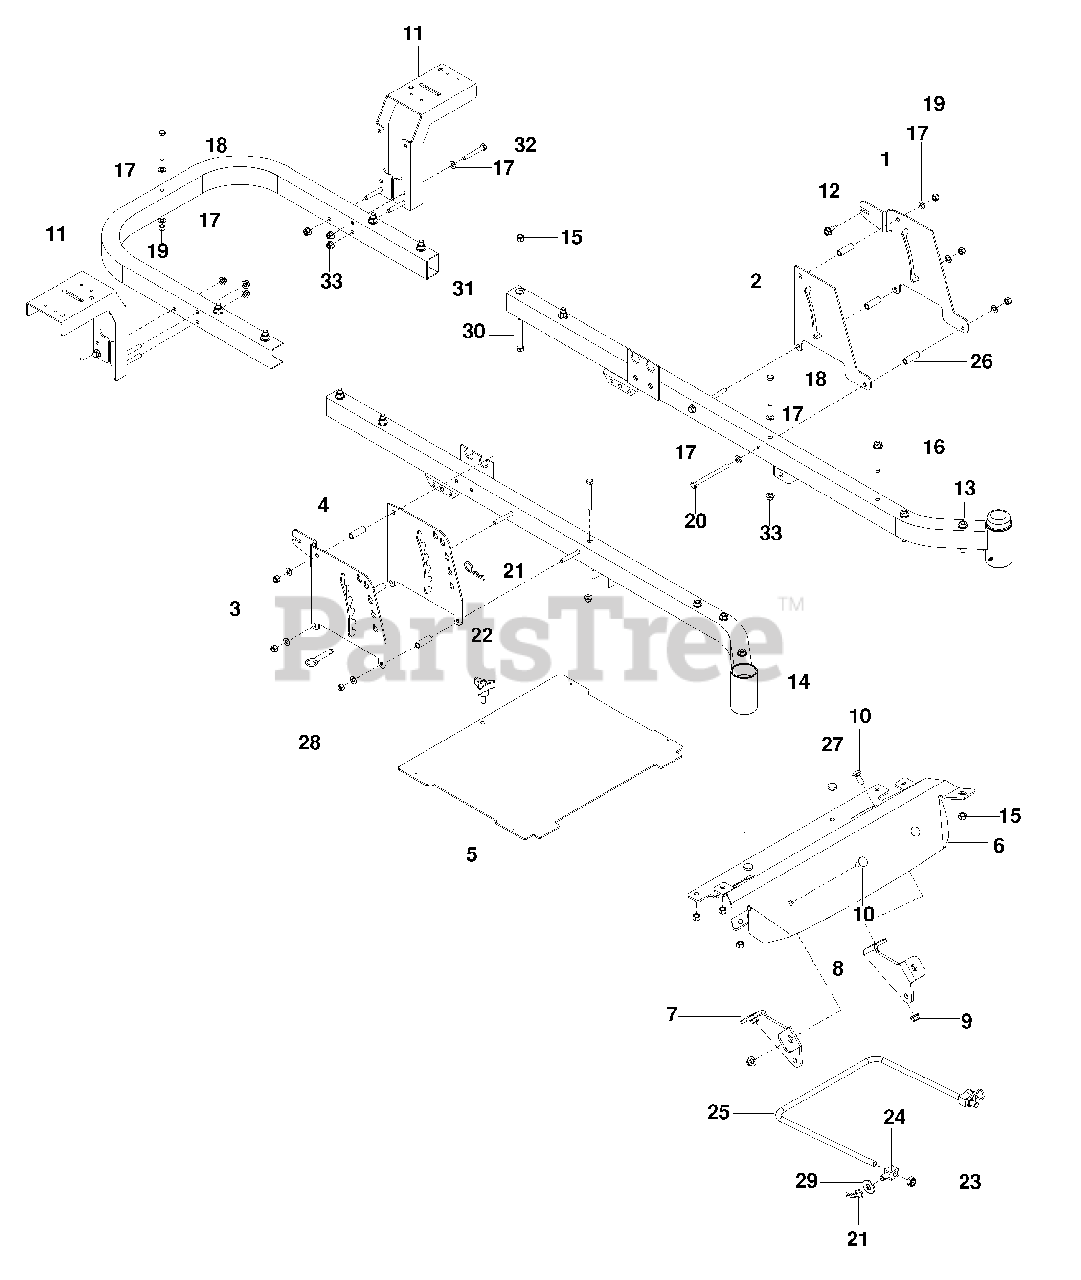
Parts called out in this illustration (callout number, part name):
1	PLATE, OUTER BRAKE BLK
2	PLATE, BRAKE LATCH BLK
3	PLATE, LIFT OUTER BLK
4	PLATE, LIFT INNER BLK
5	FOOT PLATE w/DECALS
6	FOOT REST ORG
7	MOUNT, STRUT RT BLK
8	MOUNT, STRUT LT BLK
9	NUT 3/8-16 HEX FLG NYLOC
10	RHSNB 3/8-16 x 1
11	SUPPORT, FENDER BLK
12	BOLT 5/16-18 x 3/4 THD FRM
13	FRAME, FRONT RT ORG
14	FRAME, FRONT LT ORG
15	NUT 3/8-16 HEX NYLOC
16	BOLT 3/8-16 x 25/8 THD FRM
17	WASHER 5/ SAE FLT
18	HCS 5/16-18 x 2 3/4
19	NUT 5/16-18 HEX NYLOC
20	HCS 5/16-18 x 4
22	KNOB w/ STUD
23	NUT 7/16-14 HEX NYLOC
25	LINK, FRONT SUSPENSION
26	SPACER 1/2 OD x 1 1/2
27	GROMMET, BUMPER
29	WASHER 1/2 FLT
30	HCS 3/8-16 x 3
31	WASHER 3/8 SAE FLT
32	HCS 5/16-18 x 2 1/4
33	NUT 5/16-18 FLANGE NYLOC
